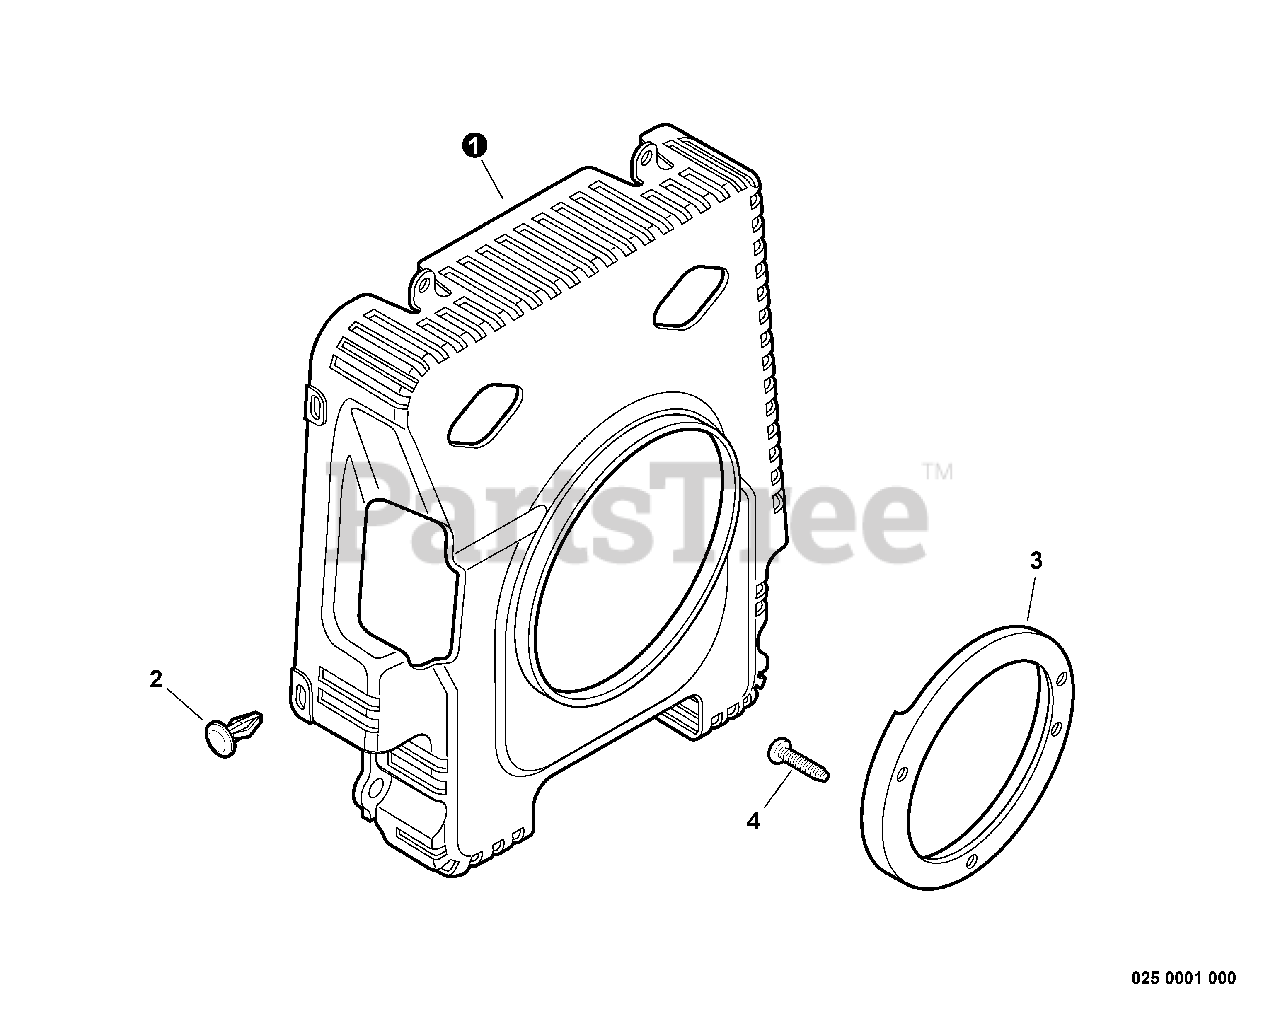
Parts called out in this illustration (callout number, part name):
1	GUARD, DEBRIS
3	DUCT, AIR
4	SCREW - 5X16 -- TAPPING
